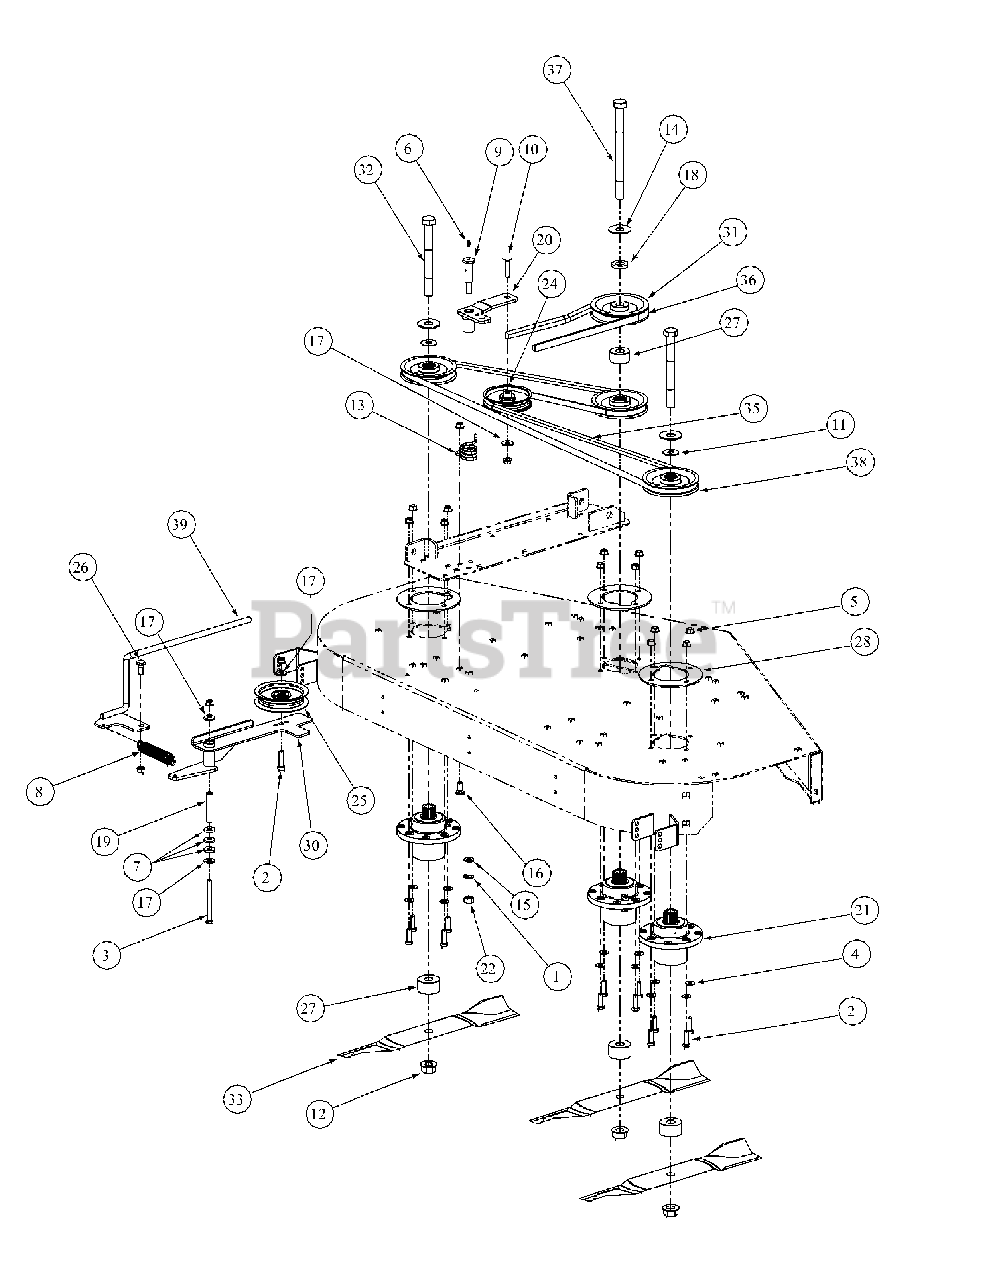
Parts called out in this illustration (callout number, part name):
1	Lock Washer, 7/16
2	Hex Cap Screw, 3/8-16 x 1-1/2
3	Hex Cap Screw, 3/8-16, 4.00
4	Flat Washer, 3/8
5	Hex Nut, Flange Lock, 3/8-16
6	Grease Fitting, 1/4-28 x 3/16
7	Idler Washer
8	Extension Spring, 1.0 OD x 5.125
9	Shoulder Screw, 7/16-14
10	Hex Carriage Screw, 3/8-16, 1.75
11	Spacer, .812 ID x .218 LG
12	Flange Hex Nut, 3/4-16
13	Torsion Spring Idler
14	Flat Washer, .781 ID, 2.00 OD, .105
15	Flat Washer, .469 ID, .875 OD, .105
16	Carriage Bolt, 3/8-16 x 1
17	Flat Washer, .406 ID, 1.0 OD, .105
19	Spacer, .39 ID x .625 OD x 2.75
20	Idler Arm Assembly, Deck Spindle
21	Spindle Assembly, Aluminum Fab Deck
22	Hex Nut, 7/16-14
24	Flat Pulley
25	Idler Pulley, 4.06 OD w/Deep Plan Flanges
26	Shoulder Screw, .50 x .27 LG, 3/8-16
27	Spacer, .760 ID x 2.000 OD x 1.1
28	Plate Support, Cast Aluminum Spindle
30	Idler Arm Assembly, Flat Top Bearing
31	V Pulley, 5.25 OD
32	Hex Cap Screw, 3/4-16, 7.00
33	Hi-Lift Blade, 19.0, 0.756
35	V Belt, A Section x 114.3
36	V Belt, B Section x 87.3
37	Hex Cap Screw, 3/4-16, 9.00
38	V Pulley, 5.00 OD
39	Rod Fab Deck Spring Tension
